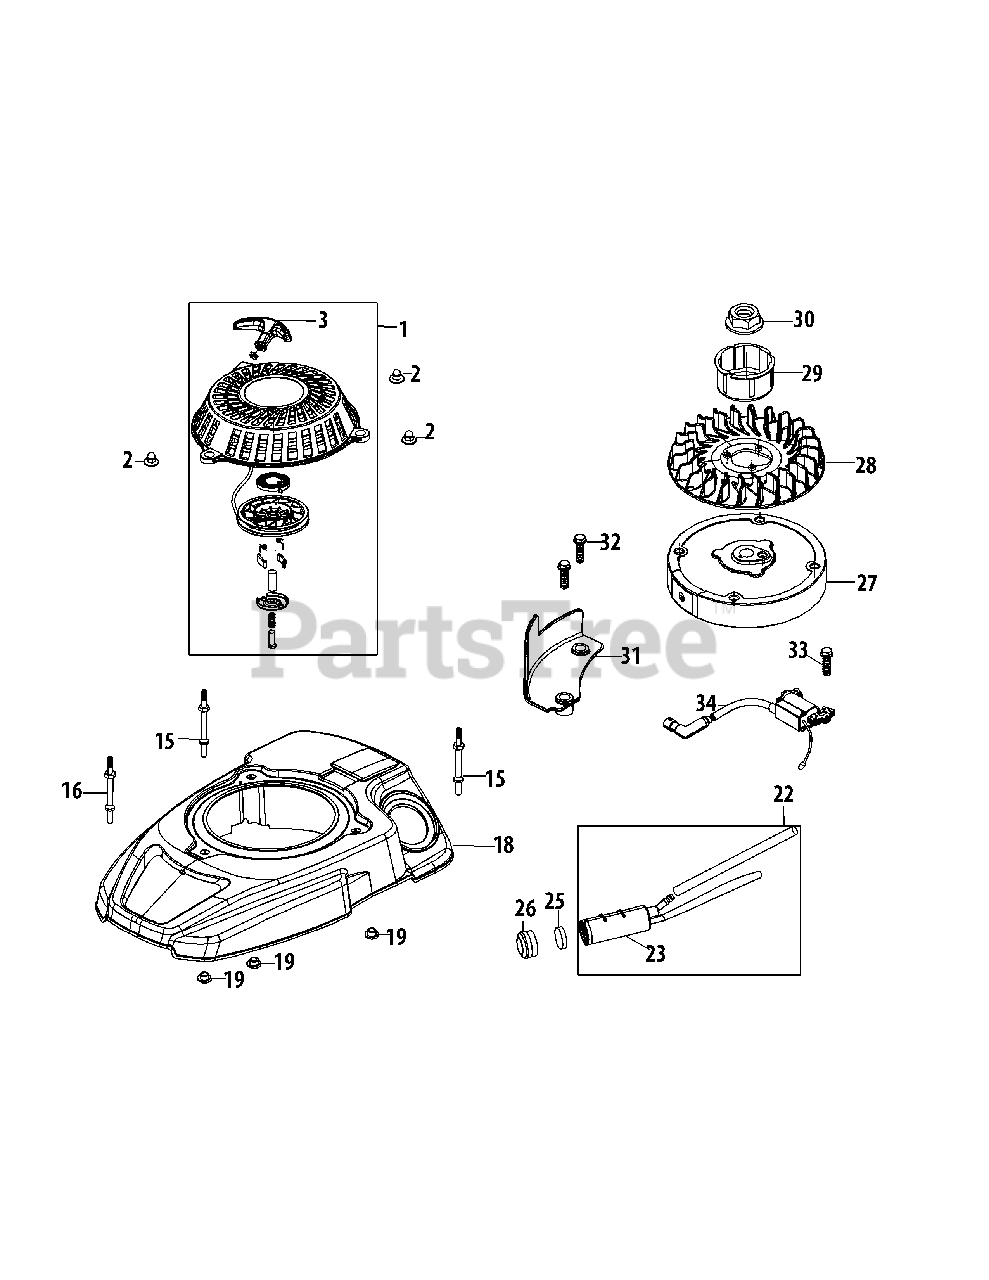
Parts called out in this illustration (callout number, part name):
1	Starter Recoil Assembly
2	Starter Acorn Nut
3	Starter Handle
15	Starter/Shroud Rear Stud M6×78.5
16	Starter/Shroud Front Stud M6×74
18	Engine Shroud
19	Engine Shroud Spacer
22	Carbon Canister Assembly
23	Carbon Canister
25	Carbon Canister Filter
26	Carbon Canister Filter Cap
27	Flywheel
28	Cooling Fan
29	Starter Cup
30	Flywheel Nut M14
31	Engine Brake Cover Plate
31	(Mtd Srvc Kit) Short Block
32	Bolt M6×25 Ign/Brake/Cvr Plt
33	Bolt M6×20 Ignition Coil
34	Ignition Coil Assembly
